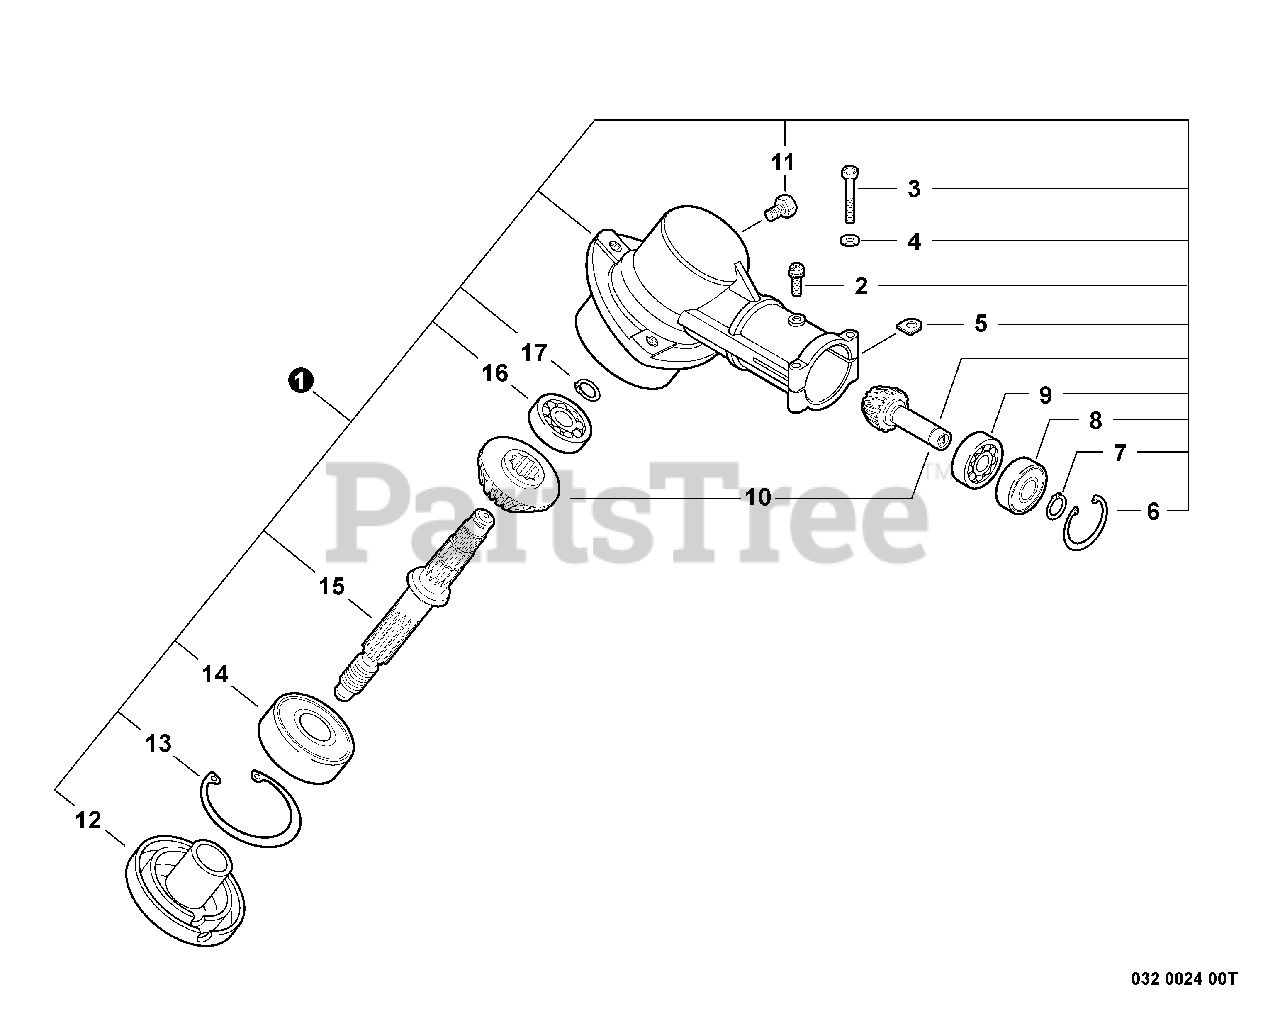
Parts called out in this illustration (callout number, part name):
1	GEAR CASE ASSY
2	SCREW - 5X12
3	BOLT - 5X35
4	WASHER - 5
6	RING, RETAINING - 22
7	RING, RETAINING - 10
8	BEARING, BALL - 6900Z
9	BEARING, BALL - 6900
10	GEAR SET
11	BOLT - 8X8
12	ADAPTOR, BLADE - UPPER
13	RING, RETAINING - 42
14	BEARING, BALL - 609
15	GEAR - SHAFT
16	BEARING, BALL - 629
17	RING, RETAINING - 12
